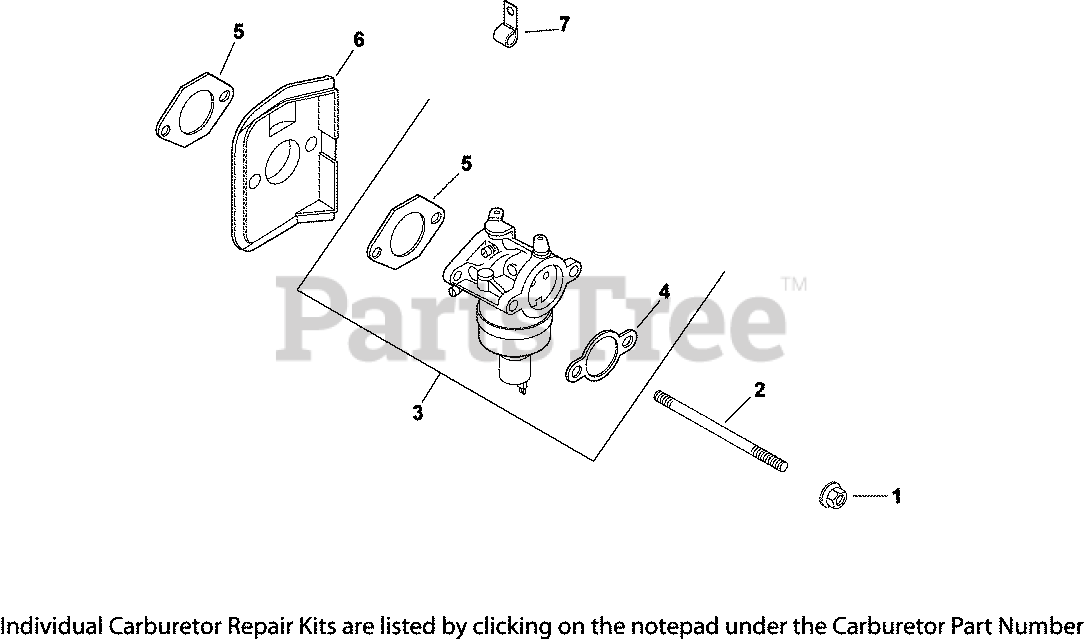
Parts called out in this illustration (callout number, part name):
1	NUT, FLG M6X1.0
2	STUD,M6X1.0X116
3	KIT, CARBURETOR w/GASKETS
4	GASKET, AIR CLEANER BASE
5	GASKET, CARBURETOR
6	DEFLECTOR, HEAT
7	CLIP, CABLE
